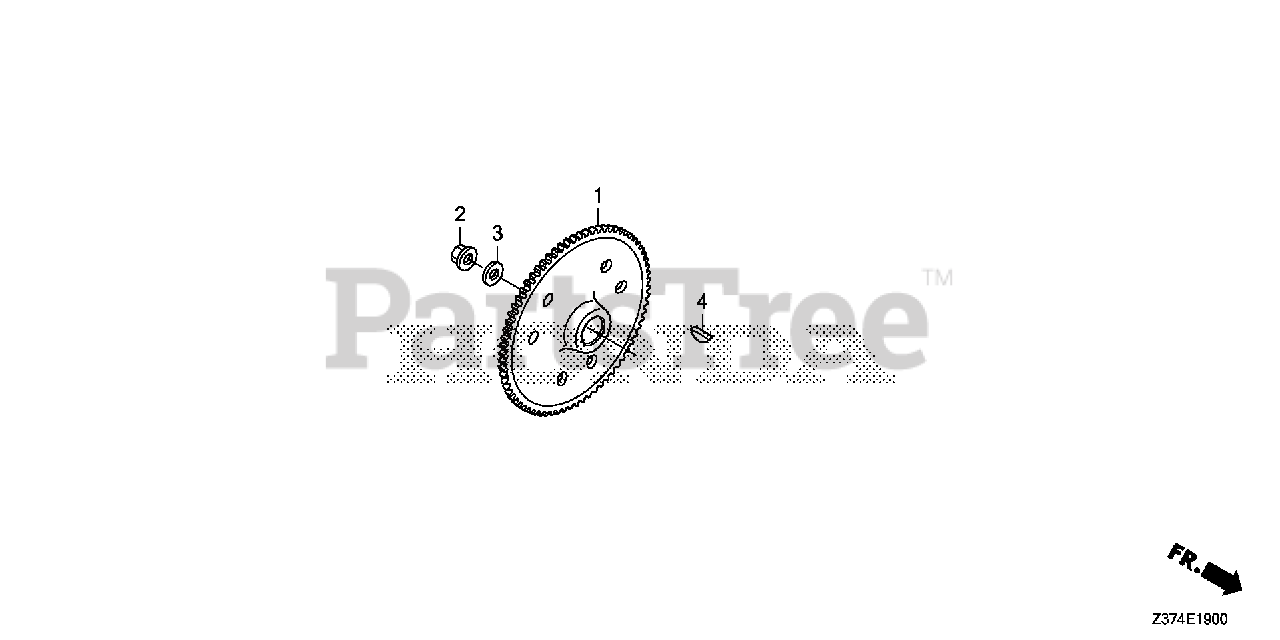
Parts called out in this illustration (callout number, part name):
2	NUT, SPECIAL (16MM) (1)
3	WASHER, FLYWHEEL
4	KEY, SPECIAL WOODRUFF (25X18)
